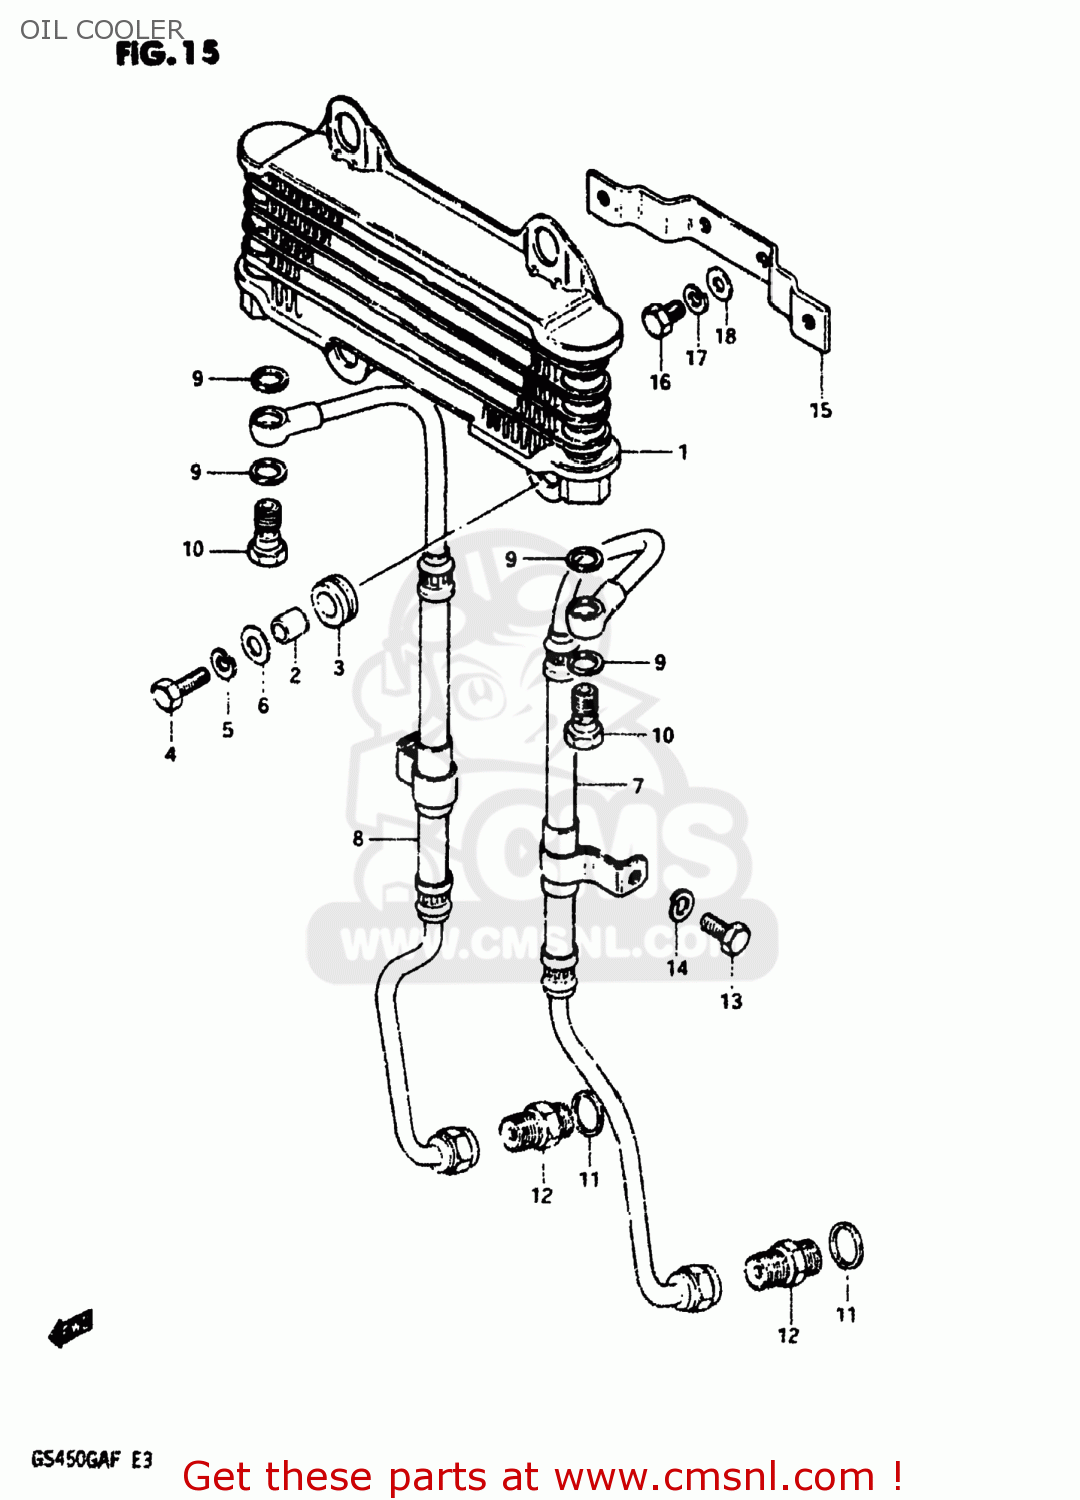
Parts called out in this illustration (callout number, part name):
1	COOLER ASSEMBLY,OIL
2	SPACER (6.8X10X10)
3	CUSHION
4	BOLT
5	WASHER,LOCK
6	WASHER (6.5X18X1.6)
7	HOSE,ENGINE OIL,RIGHT
8	HOSE,ENGINE OIL,LEFT
9	GASKET(12X16.5X1.5) (NAS)
10	BOLT UNION
11	GASKET(14X20X1.5) (NAS)
12	BOLT UNION
13	BOLT
14	WASHER,LOCK
15	BRACKET,OIL COOLER
16	BOLT
17	WASHER,LOCK
18	WASHER
